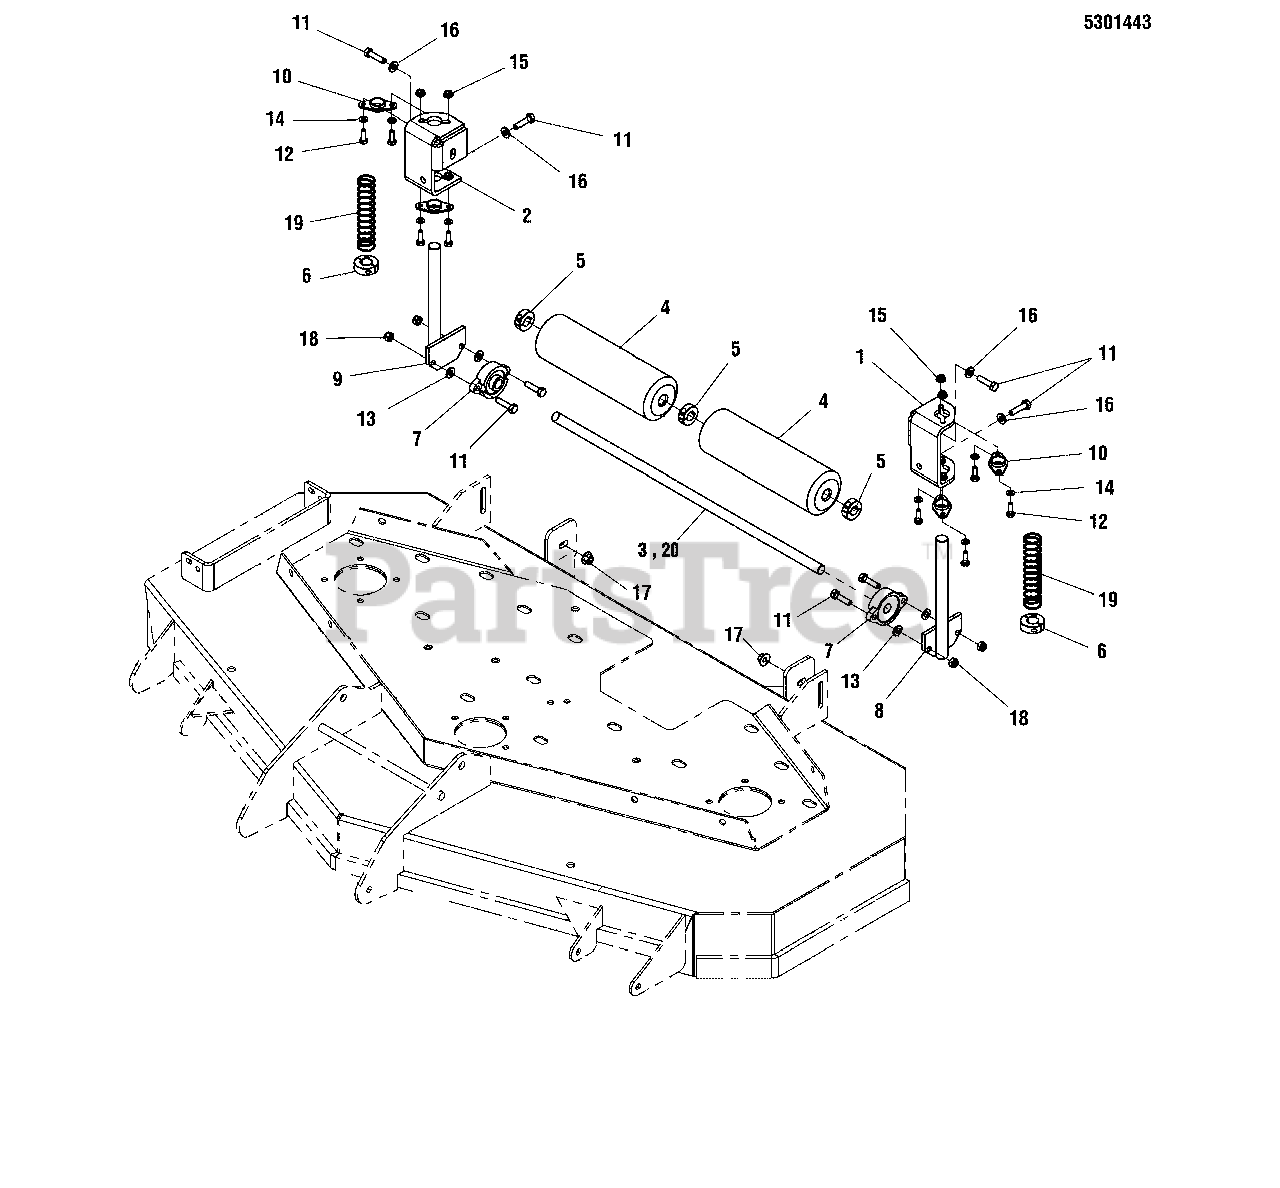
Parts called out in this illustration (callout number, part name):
1	WELD, MOUNT, STRIPER, LH - ORG
2	WELD, MOUNT, STRIPER, RH - ORG
3	SHAFT, ROLLER
4	ROLLER, DECK
5	COLLAR, 5/8 SPLIT
6	COLLAR, 3/4 DOUBLE SPLIT
7	BEARING-FLANGE, 5/8
8	SHAFT, STRIPER GUIDE WELD - LH
9	SHAFT, STRIPER GUIDE WELD - RH
10	BUSHING, FLANGE
11	BOLT, 5/16-18 X 1-1/4 GD5 YZ
12	BOLT, 1/4-20 X 3/4 GD5 YZ
13	WASHER, 5/16 SAE
14	WASHER, 1/4 SAE (5025154)
15	NUT, 1/4-20 HEX SERR. FLANGE
16	WASHER, 5/16 GD.9 FLAT
17	NUT, 5/16-18 HEX SERRATED FLANGE (LARGE)
18	NUT, 5/16-18 HEX NYLON LOCK
19	SPRING, COMP, 1.1 X OD. X .085 WIRE X 5
20	BAR, 5/8 CRR 21.87 LONG
